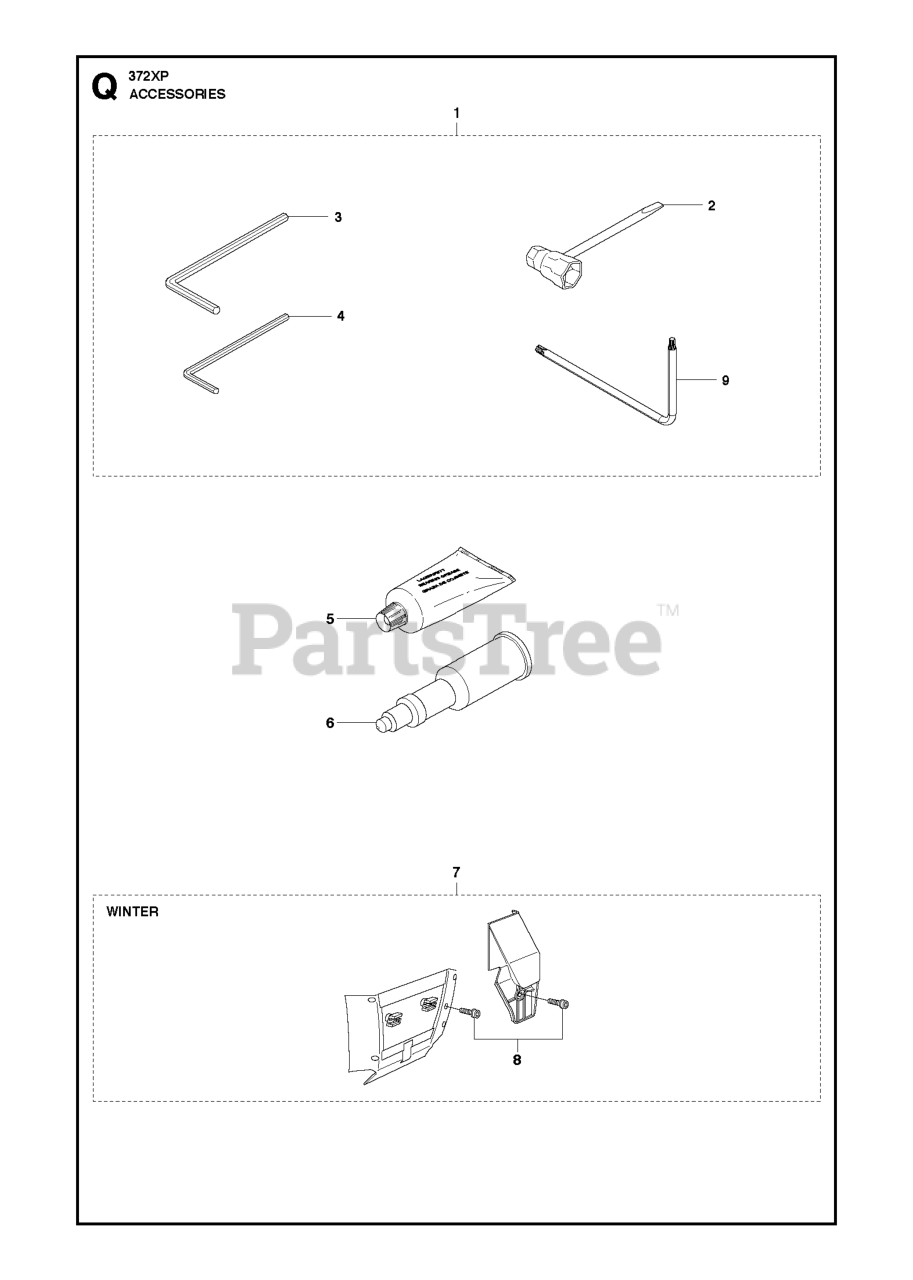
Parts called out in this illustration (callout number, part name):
2	COMBI TOOL
3	L-SPANNER
4	L-SPANNER
5	GREASE
6	Grease Gun
7	WINTER KIT
9	WRENCH
